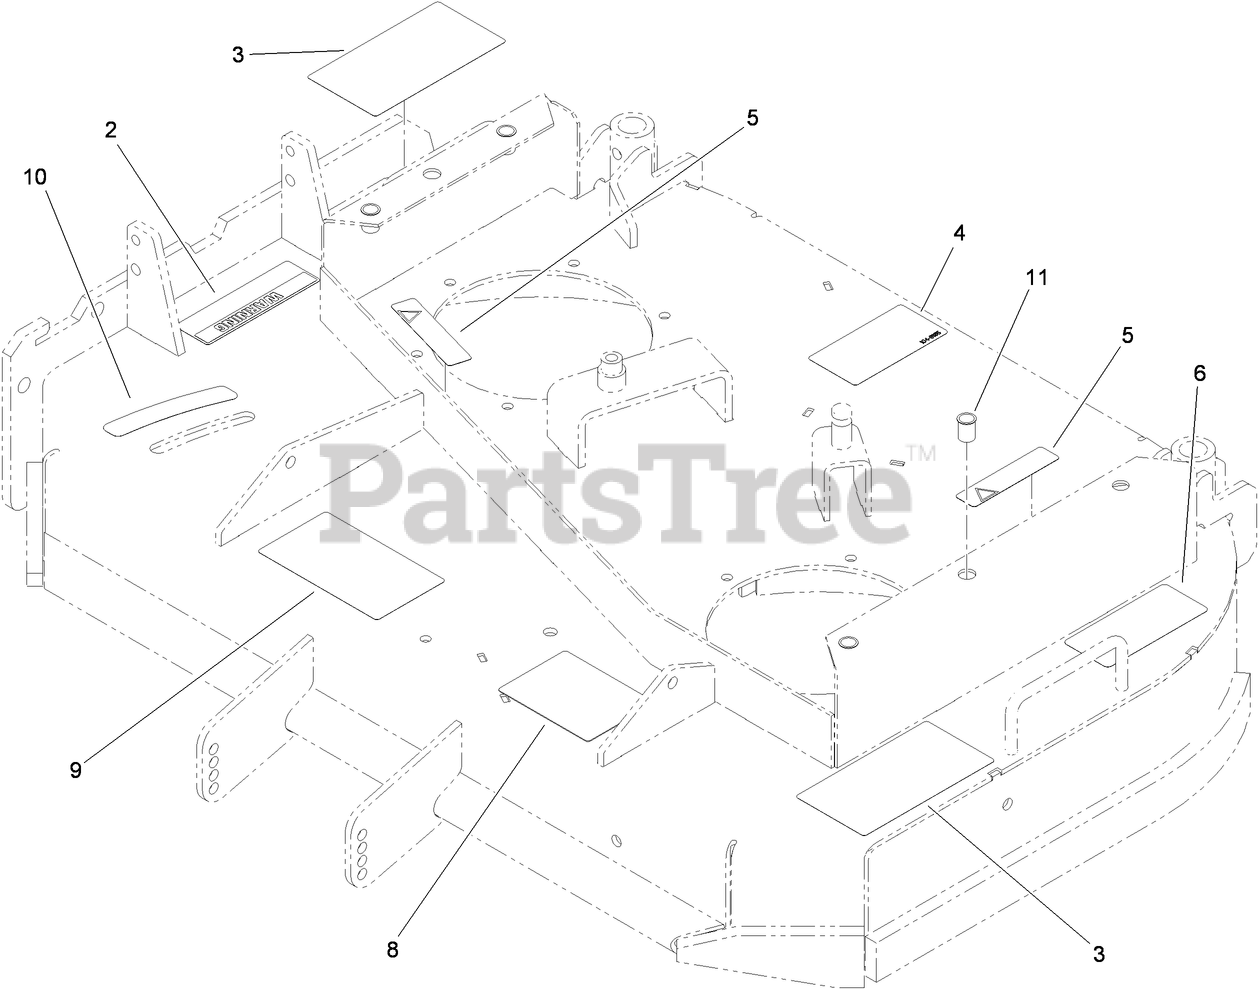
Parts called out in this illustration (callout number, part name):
2	DECAL-WARNING, DEFLECTOR
3	DECAL-DANGER
5	DECAL-WARNING
6	DECAL-TORQUE, BLADE BOLT
8	DECAL-ANTI SCALP
9	DECAL-ADJUSTMENT, BAFFLE
10	DECAL-SETTING, BAFFLE
11	INSERT-NUT
